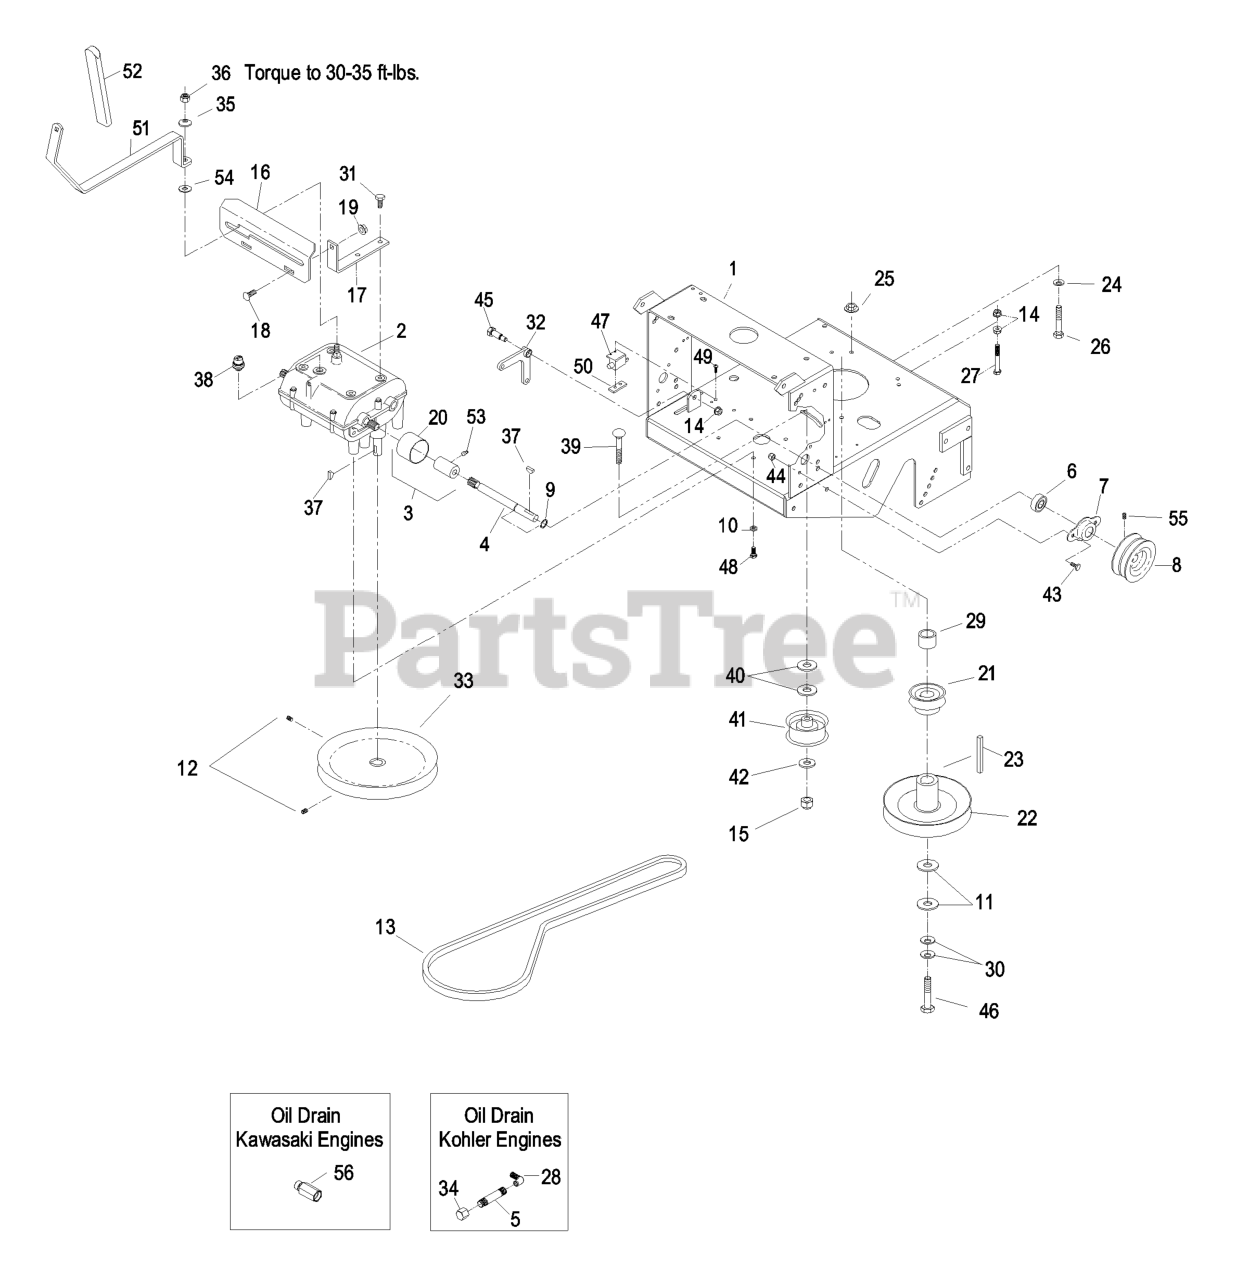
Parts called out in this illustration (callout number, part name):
3	ASM,COUPLER/ZERK
4	SHAFT-TRANSMISSION
5	NIPPLE
6	BEARING-SHAFT
7	FLANGE-OUTPUT
8	SHEAVE-TRANSMISSION
9	RING-RETAINING
10	WASHER-LOCK
12	SCREW-HSH
13	BELT,TRANS DRIVE
14	NUT-HHF, WHIZ
15	NUT-LOCK, NI
16	PLATE,SHIFTER W/DECAL
17	BRACKET-PLATE, SHIFT
18	BOLT-CARR
20	GUARD-COUPLER
21	SHEAVE-TRANSMISSION
23	KEY-SQUARE
24	WASHER-SPRING
26	SCREW-HH
27	SCREW-HH
28	FITTING-ELBOW-90
29	SPACER-CLUTCH
30	WASHER-SPRING
31	SCREW-HWH, THREAD CUT
32	BELLCRANK
33	SHEAVE-TRANSMISSION
34	CAP-HEX
35	WASHER-BELLEVILLE
36	NUT-LOCK
37	KEY-WOODRUFF
38	SWITCH-START, NEUTRAL
39	SCREW-HH
40	WASHER-FLAT
42	WASHER-FLAT
43	SCREW-HH
44	NUT-LOCK, NI
45	BOLT-SHOULDER
46	SCREW-HH
47	SWITCH-OPEN, NORMALLY
48	SCREW-HH
49	SCREW-PPH
50	PLATE-TAPPED
51	ASM,SHIFT LEVER
52	GRIP,FOAM
53	FITTING-GREASE
55	SCREW-SET
56	ADAPTER
